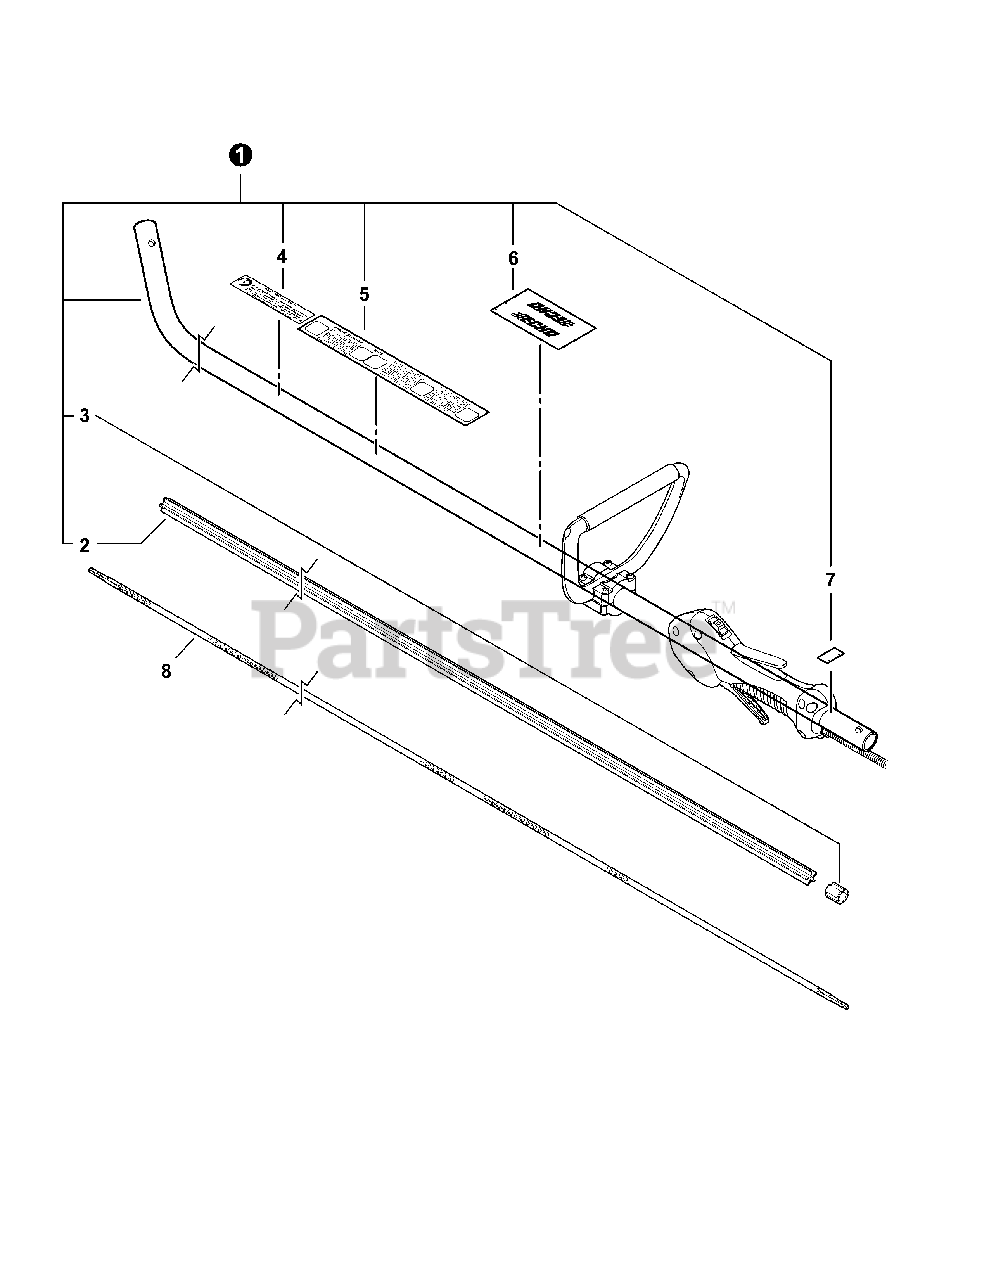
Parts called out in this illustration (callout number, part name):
1	MAIN PIPE ASY
2	LINER - FLEXIBLE
4	LABEL - CAUTION -- SPANISH
5	LABEL - CAUTION
6	LABEL - HANDLE LOCATION
7	LABEL - ALIGNMENT
8	DRIVESHAFT - FLEXIBLE
